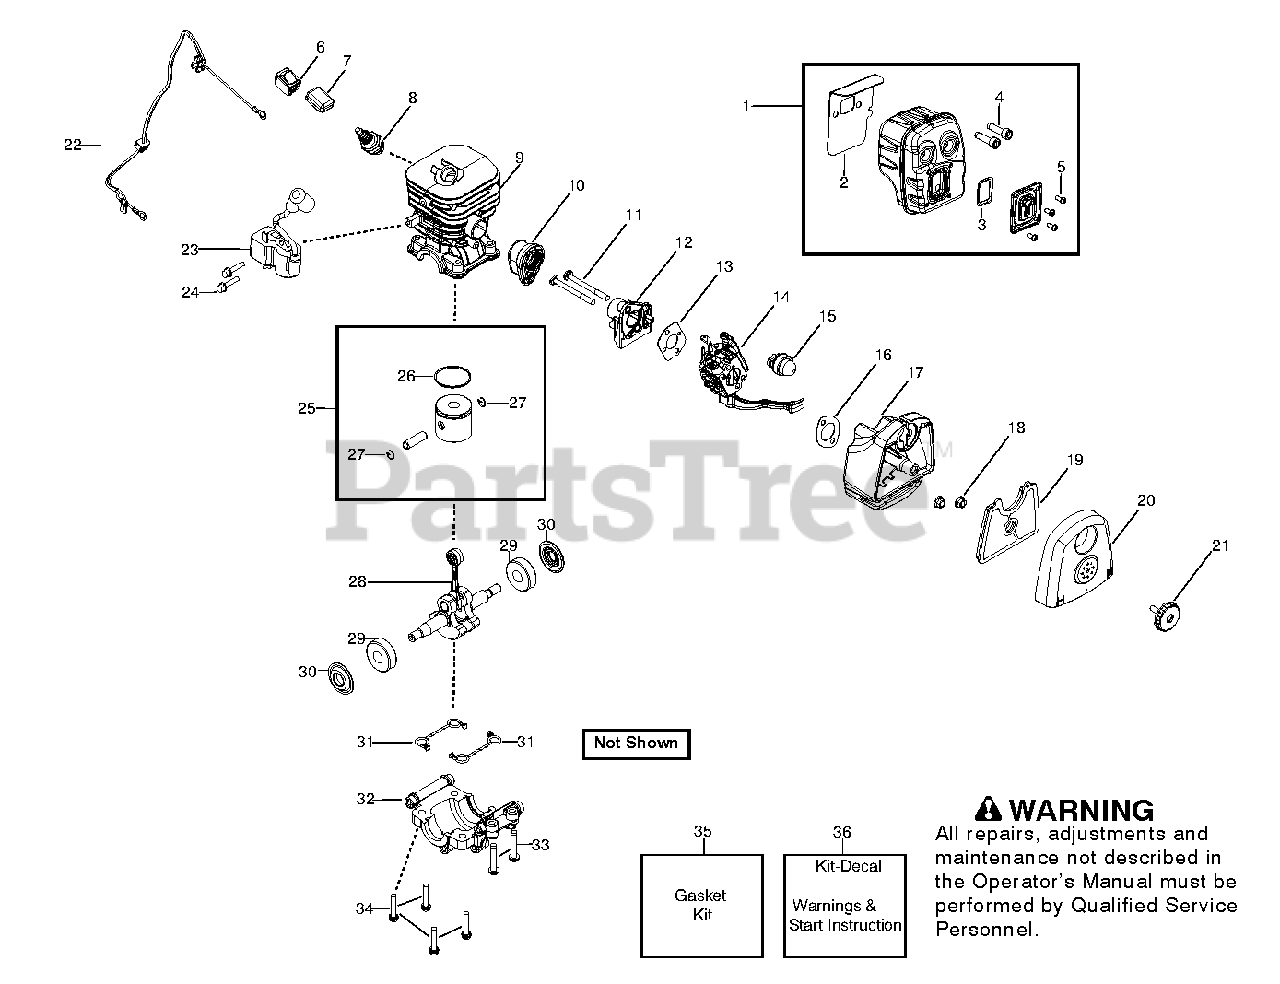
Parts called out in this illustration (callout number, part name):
1	ASSY, MUFFLER
3	KIT, SPARK SCREEN
4	BOLT MUFFLER
5	SCREW-6-19X5/16PLAST PA
6	KIT SWITCH
7	PROTECTOR, SWITCH
8	PLUG-SPARK (RCJ-6Y)
9	CYLINDER -CHROME
10	BOOT, CARB
12	PLATE, CARB
14	KIT, CARB
15	AIR PURGE
17	BASE - AIR BOX
19	FILTER, AIR
20	COVER - AIR BOX
21	ASSY - AIR BOX KNOB
22	ASSY, LEADWIRE
23	IGNITION MODULE
24	SCREW M4 X .70 TT 16MM
25	KIT - PISTON
26	RING PISTON
27	WRIST PIN RET.
28	KIT, CRANKSHAFT
29	BEARING RADIAL BALL (6201)
30	CRANKSHAFT SEAL
32	CAP - BEARING
34	B0LT, C/SHAFT 36/41
35	GASKET
36	KIT, DECAL
